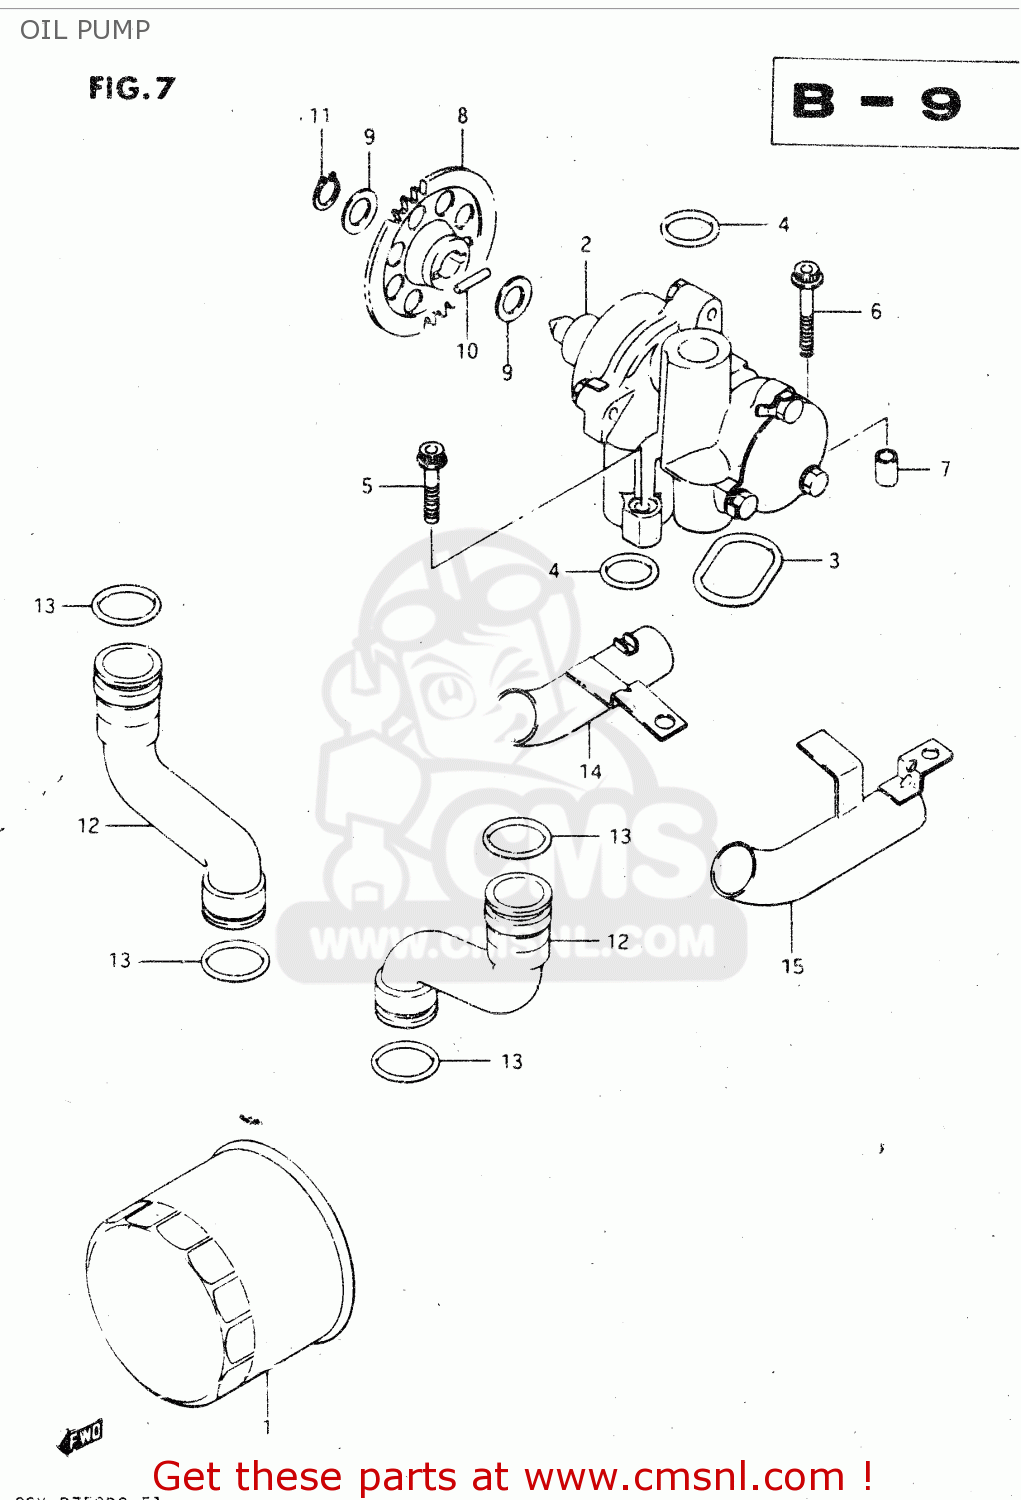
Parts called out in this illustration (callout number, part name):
1	FILTER ASSY,ENGINE OIL
2	PUMP ASSEMBLY,OIL
3	O RING,OIL PUMP
4	O RING(D:3.2,ID:17.8)
5	BOLT
6	BOLT
7	PIN
8	GEAR,OIL PUMP DRIVEN
9	SHIM
10	PIN(5X18)
11	CIRCLIP
12	HOSE,OIL
13	O-RING
14	PIPE,OIL,OUTLET,UNDER
15	PIPE,OIL,OUTLET,UNDER
